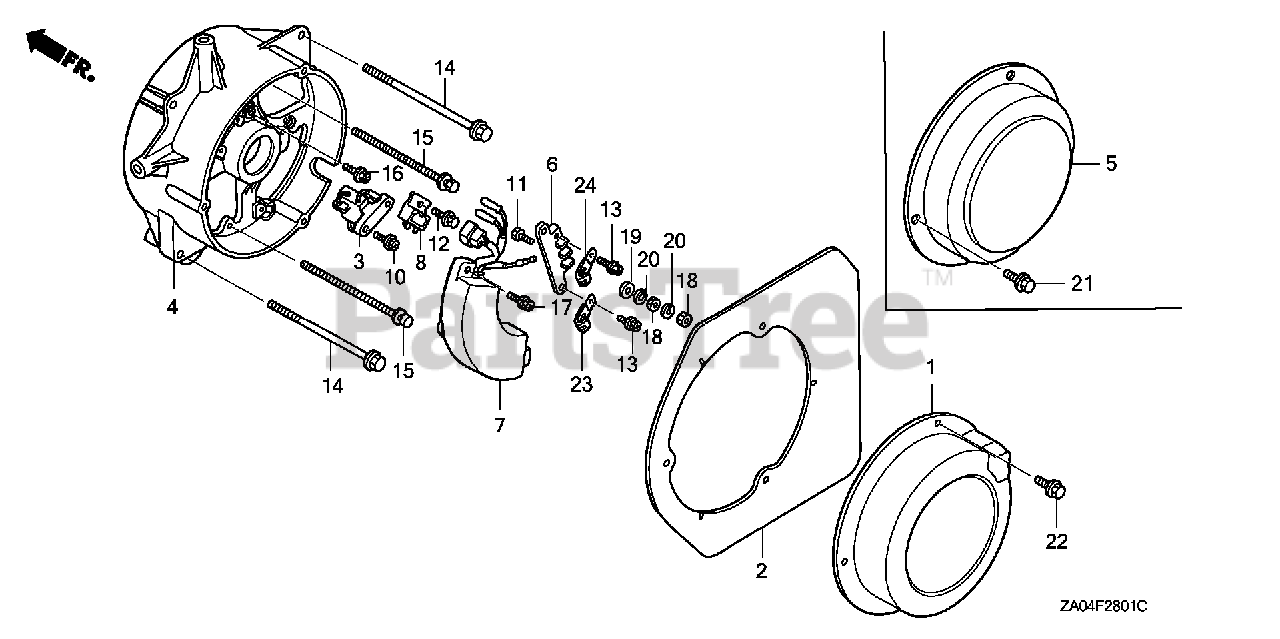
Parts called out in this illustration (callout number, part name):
3	BRUSH ASSY.
4	HOUSING, RR.
5	COVER, GENERATOR END
6	TERMINAL, VOLT CHANGE
7	REGULATOR ASSY., AUTOMATIC VOLTAGE
8	DIODE, D.C.
10	SCREW, TAPPING (5X18)
11	BOLT, HEX. (5X20)
12	SCREW, TAPPING (5X12) (GROUND CABLE)
13	SCREW, TAPPING (5X14)
14	BOLT, FLANGE (8X220)
15	BOLT-WASHER (5X210)
16	SCREW, PAN (5X12) (GROUND CABLE)
17	SCREW, TAPPING (5X16) (NOT AVAILABLE)
18	NUT, HEX. (5MM)
19	WASHER, PLAIN (5MM)
20	WASHER, SPRING (5MM)
21	BOLT, FLANGE (6X10)
23	CLAMP A, WIRE
24	CLAMP B, WIRE
